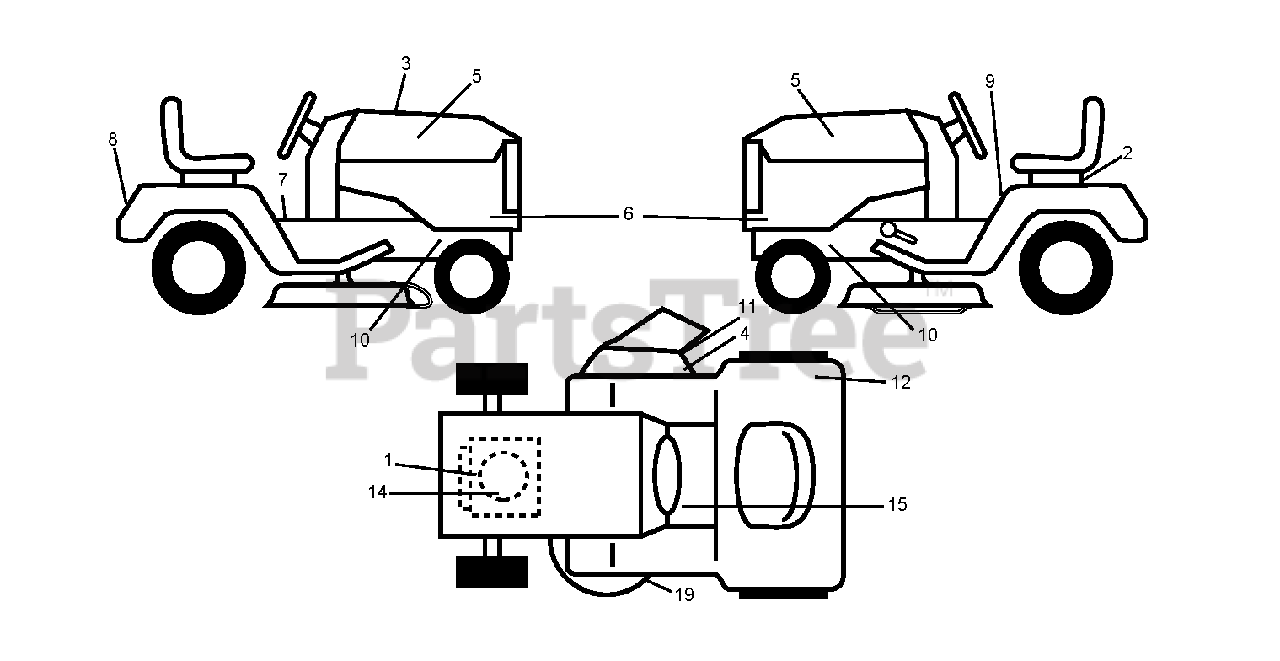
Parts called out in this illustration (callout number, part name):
2	DECAL BTRY SYMBOLS
4	DECAL, DEFLECT WARNING
7	DECAL PARK BRAKE
11	DECAL.INTERNATIONL.CUTFINGER
19	DECAL.V-BELT.SCHEMATIC.36/38/9
